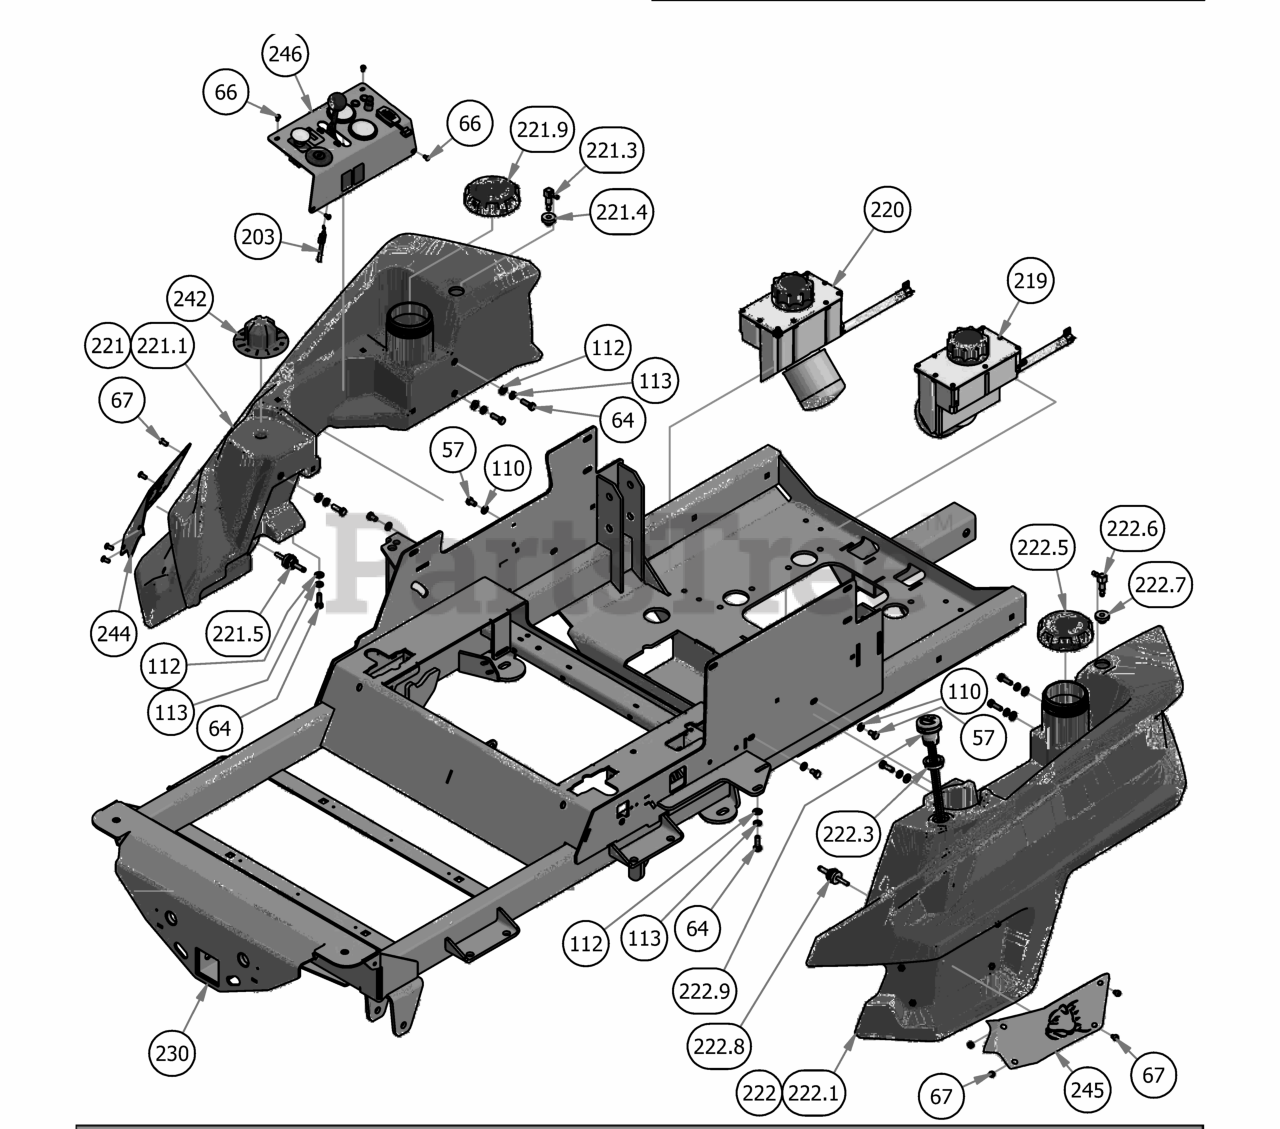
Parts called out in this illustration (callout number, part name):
57	5/16"-18 x 1/2 GR5 Hex bolt zink
64	5/16" x 1" Bolt
66	10-32 x 3/8" Button Socket Head Bolt
67	1/4" x 1/2" BS C/S 18-8 SS
110	1/4" Flat Washer
112	5/16" Flat Washer
113	5/16" Lock Washer
203	Diesel Throttle Cable
219	LH Rogue Hydro Tank Assy
220	RH Rogue Hydro Tank Assy
221	2019 Right Renagade Fuel Tank (diesel)
221.1	2019 Right Fuel Tank (Diesel)
221.3	90 Degree Elbow Fitting
221.4	Nitrile Bushing
221.5	Fuel Pick-up
221.9	Diesel Fuel Cap
222	2019 Left Renegade Fuel Tank (Diesel)
222.1	2019 Left Fuel Tank (Diesel)
222.3	Fuel Gauge Grommet
222.5	Diesel Fuel Cap
222.6	90 Degree Elbow Fitting
222.7	Nitrile Bushing
222.8	Fuel Pick-up
222.9	Fuel Gauge
230	2019 Horizontal Diesel Frame
242	2019 Deck Height Dial
244	2019 Outlaw Fuel Tank Insert - Right
245	2019 Outlaw Fuel Tank Insert - Left
246	Renegade Control Panel Assembly
